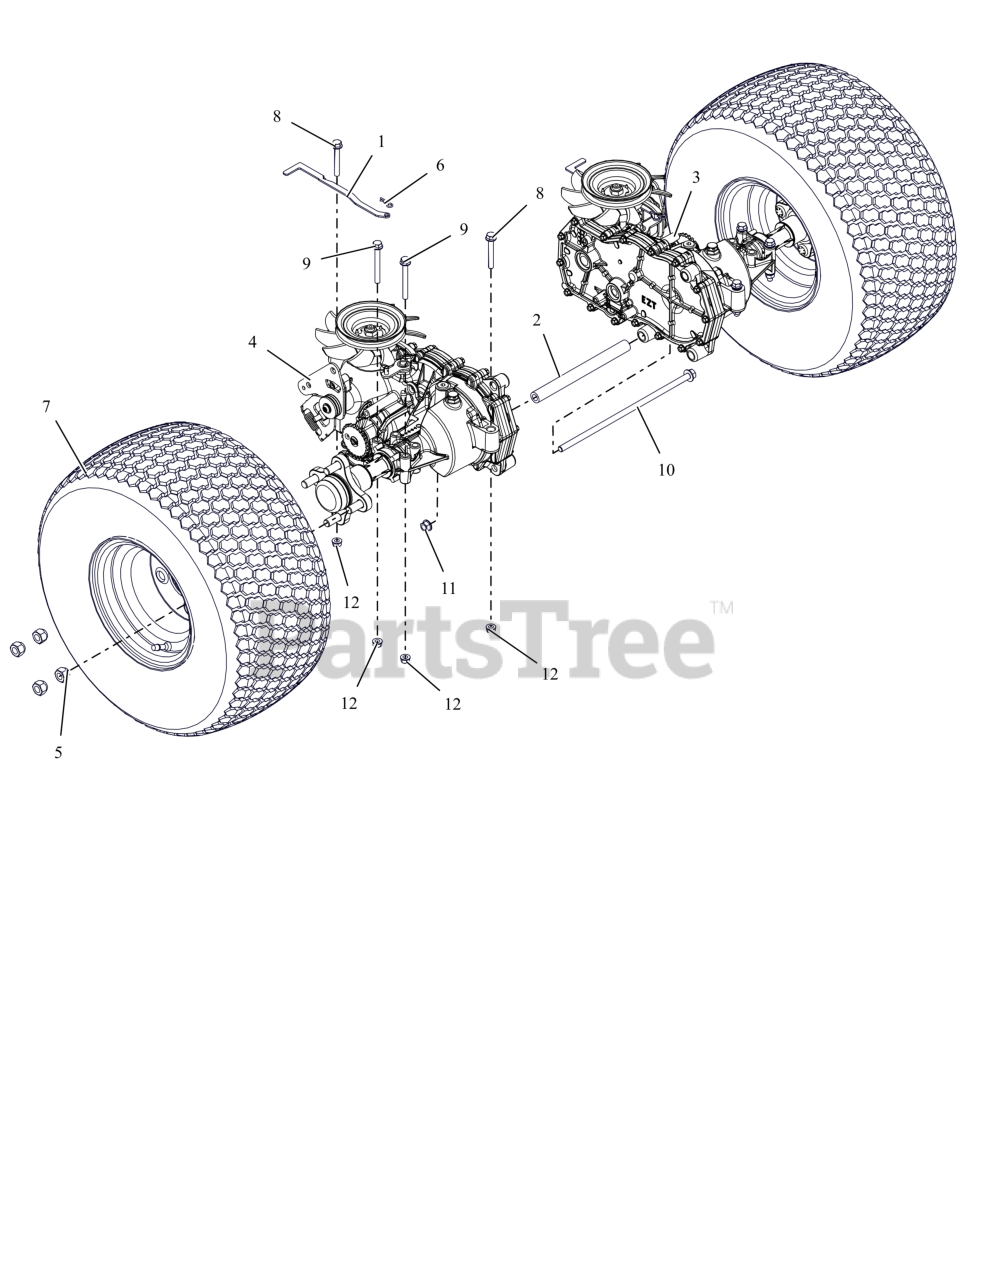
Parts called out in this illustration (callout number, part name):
1	BRKT, DUMP VALVE
2	TUBE, TRANSAXLE BRACE 8.18LG
3	TRANSAXLE
4	TRANSAXLE
5	NUT, WHEEL .50-20 ZCC
6	PIN, HAIR #213 .08X1.19 ZCC
7	ASSM TIRE\WHEEL, 20 X 10 -8
7	TIRE, 20X10.00-8
8	BLT,HEX-FLG .31-18X2.25 G5 ZCC
9	BLT,HEX-FLG .31-18X2.75 G5 ZCC
10	BLT,HEX-FLG .38-16X11.5 G5 ZCC
11	NUT-LK-CTR-FLG .375-16 GF ZCC
12	NUT,LK-CTR-FLG .31-18 GF ZCC
